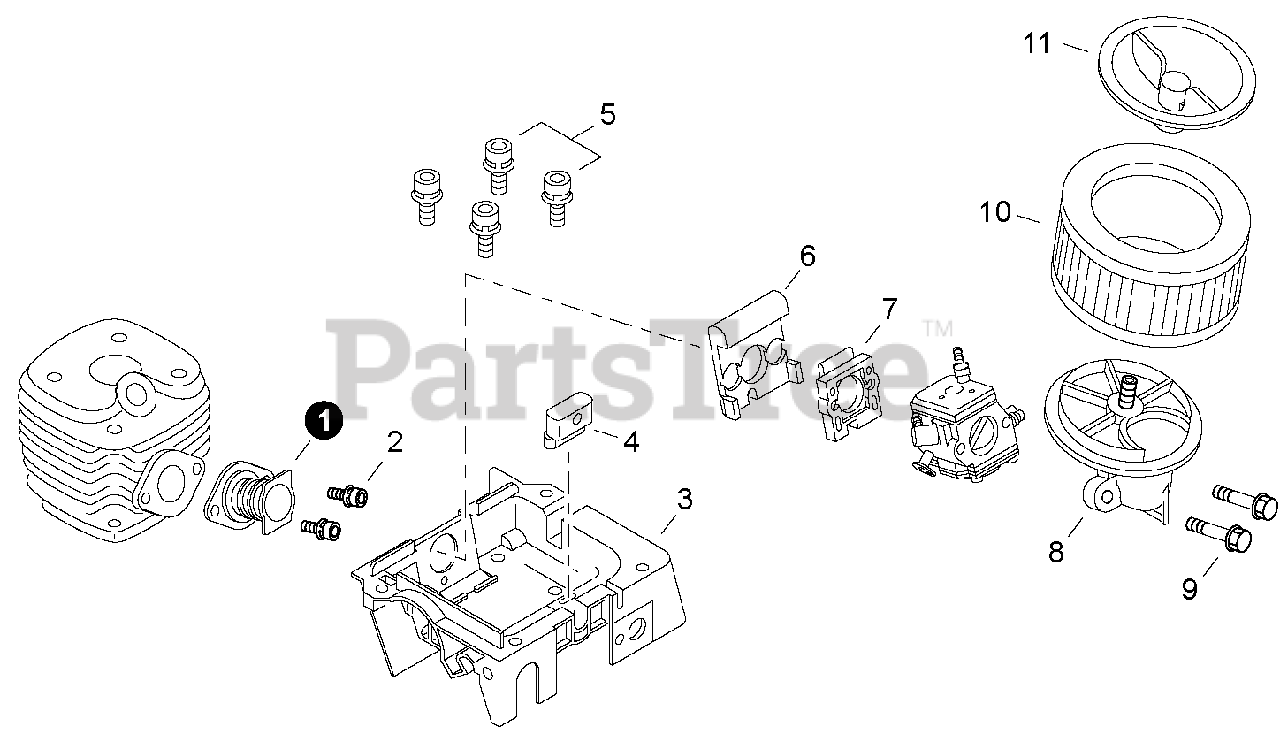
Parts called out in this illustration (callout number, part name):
1	BELLOWS, INTAKE
2	SCREW - 5X14
3	CASE, CARBURETOR
4	CUSHION
5	SCREW - 5X20
6	BRACKET
7	INSULATOR, INTAKE
8	MOUNT, AIR FILTER
9	SCREW - 5X50
10	FILTER, AIR
11	COVER, AIR FILTER
